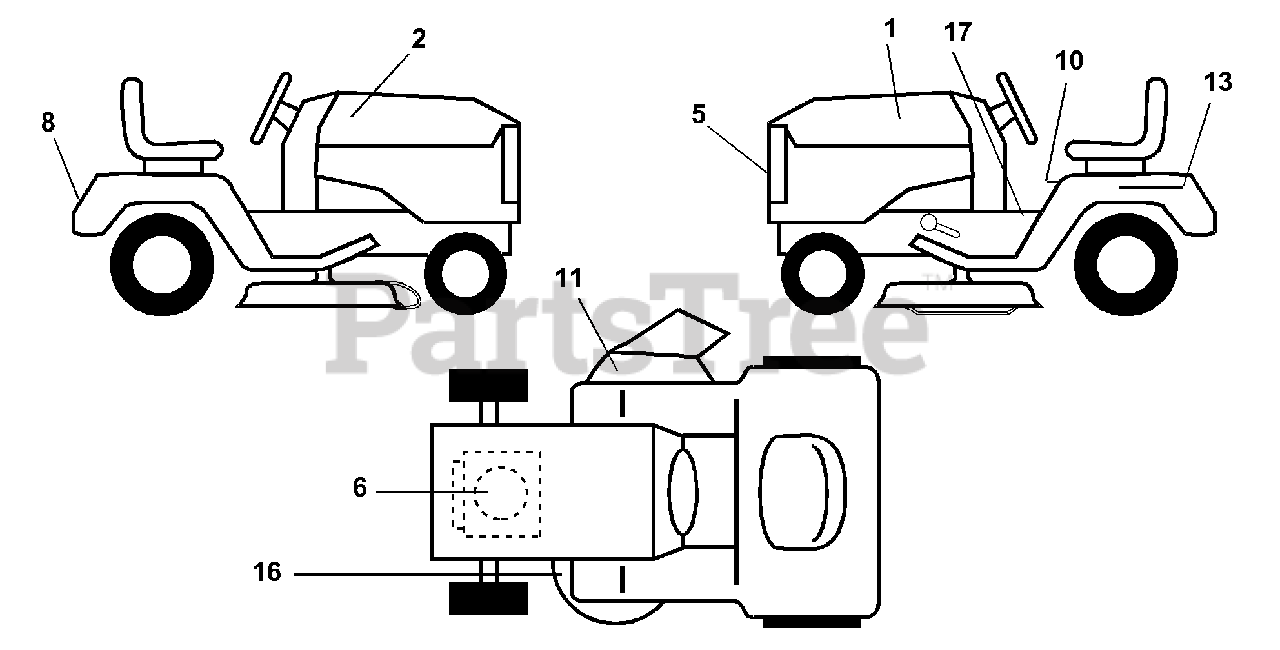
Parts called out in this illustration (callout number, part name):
1	Decal, Hood, L.H., Husqv.
2	Decal, Hood, R.H., Husqv.
5	Decal, Logo, Grill
6	Decal, Engine
8	Decal, Logo, Fender
10	Decal Caution Fender
11	Decal, Warning, Cut Finger, (Multi-Lang)
13	Decal, Caution, Battery
16	Decal, V-Belt Sch.
17	Decal, Inst. Oper.
